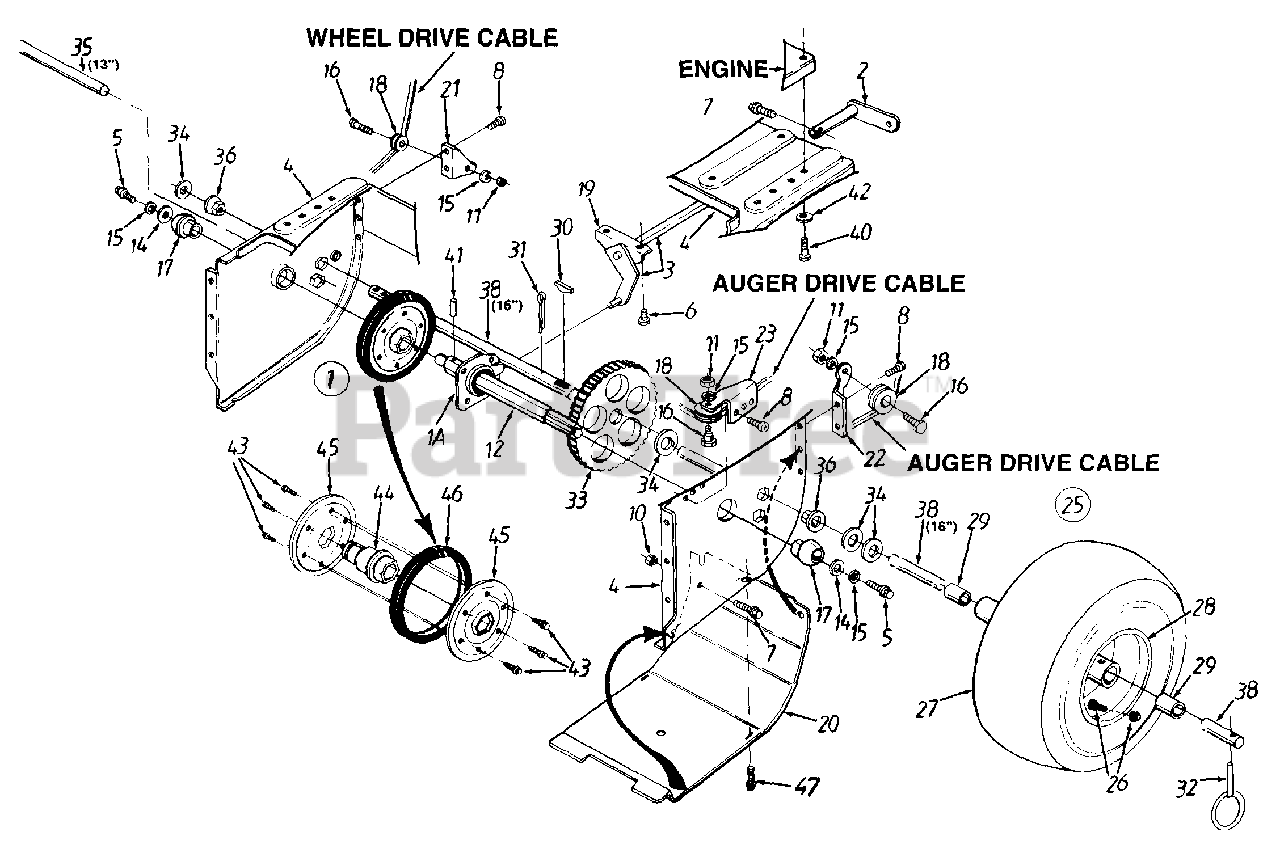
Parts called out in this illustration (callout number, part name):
1	Friction Wheel Ass'y. Comp.
1A	Friction Wheel Brg. Ass'y.
3	Shift Rod Ass'y.
6	Hex Tap Scr. 1/4-20 x .38" Lg.
7	Hex Wash. Hd. TT-Tap Scr. 1/4-20 x 1" Lg.
8	Torx Mach. AB-Tap Scr. 1/4 x .62" Lg.
10	Hex Nut 1/4-20 Thd.
11	Hex Jam Nut 1/4-20 Thd.
12	Gear Shaft
14	Fl-Wash .265" I.D. x .938" O.D.
15	L-Wash. 1/4" I.D.
16	Shld. Bolt 5/16 Dia. x .35" Lg.
17	Ball Brg. w/Snap Ring
18	Cable Roller Guide
30	#9 Hi-Pro Key 3/16" x 3/4" Dia.
31	Cotter Pin 5/32" x 1-1/4" Lg.
32	Klik Pin
33	79 Tooth Gear
34	Fl-Wash 76" I D x 1 49" 0 D
35	Wheel Axle
36	Hex Flange Brg .752" I.D.
38	Wheel Axle
40	Hex Bolt 3/8-16 x 1.25"
41	Spr. Roll Pin 1.12" Lg.
42	Fl-Wash. 406" I.D. x 1" O.D.
43	Hex Wash. Hd. TT-Tap Scr 1/4-20 x 5" Lg
44	Friction Wheel Hub
45	Friction Plate
46	Friction Wheel Rubber
47	Hex Wash Tap Scr 3/8" Lg
